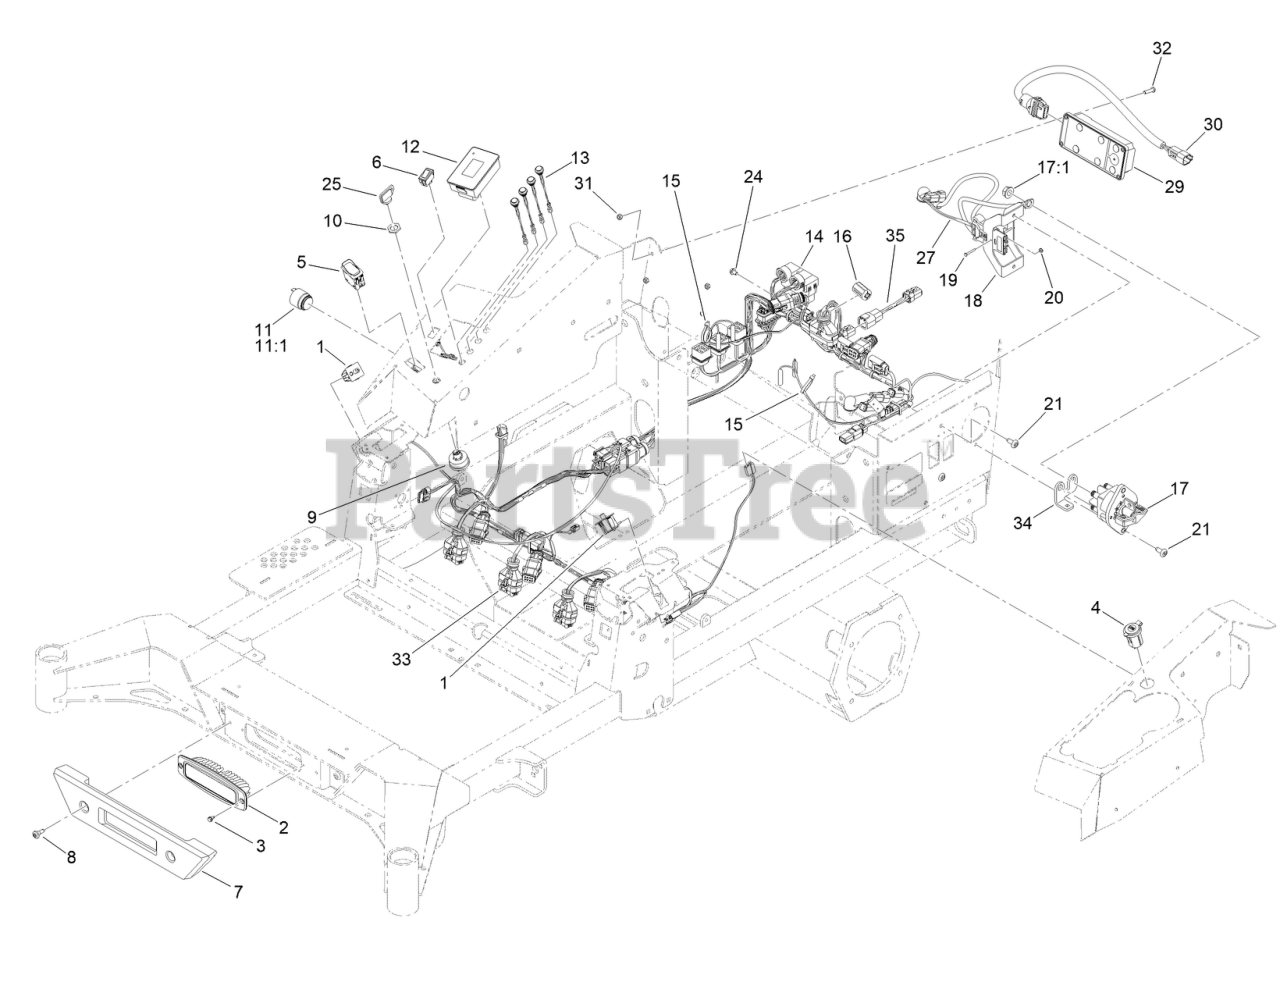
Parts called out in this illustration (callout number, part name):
1	SWITCH-PLUNGER, ON-(ON)
2	MOUNT-FLUSH, LIGHT
3	SCREW-HWH
4	PORT-POWER, USB
5	SWITCH-ROCKER, ON-NONE-ON
6	SWITCH-ROCKER
7	BUMPER-FRONT
8	SCREW-SHOULDER
9	SWITCH-KEY, SPST
11	AUDIO ALARM ASM
11:1	NUT-PLASTIC, KNURLED
12	TDM 2002
13	SWITCH-PUSHBUTTON
14	HARNESS-WIRE, MAIN
15	TIE-CABLE
16	FERRITE, SNAP-ON
17	SWITCH-DISCONNECT
17:1	NUT-HF
18	BRACKET-CHARGER, DUAL
19	SCREW
20	NUT-HEX
24	SCREW-HWH
25	KEY-IGNITION
27	HARNESS-WIRE, CHARGER PORT
29	CONTROLLER, CALAMP-NA
30	HARNESS-WIRE
31	NUT-LOCK
32	SCREW-HSBH
33	HARNESS-WIRE, DECK
34	BUSBAR-2, SWITCH
35	HARNESS-WIRE, JUMPER
